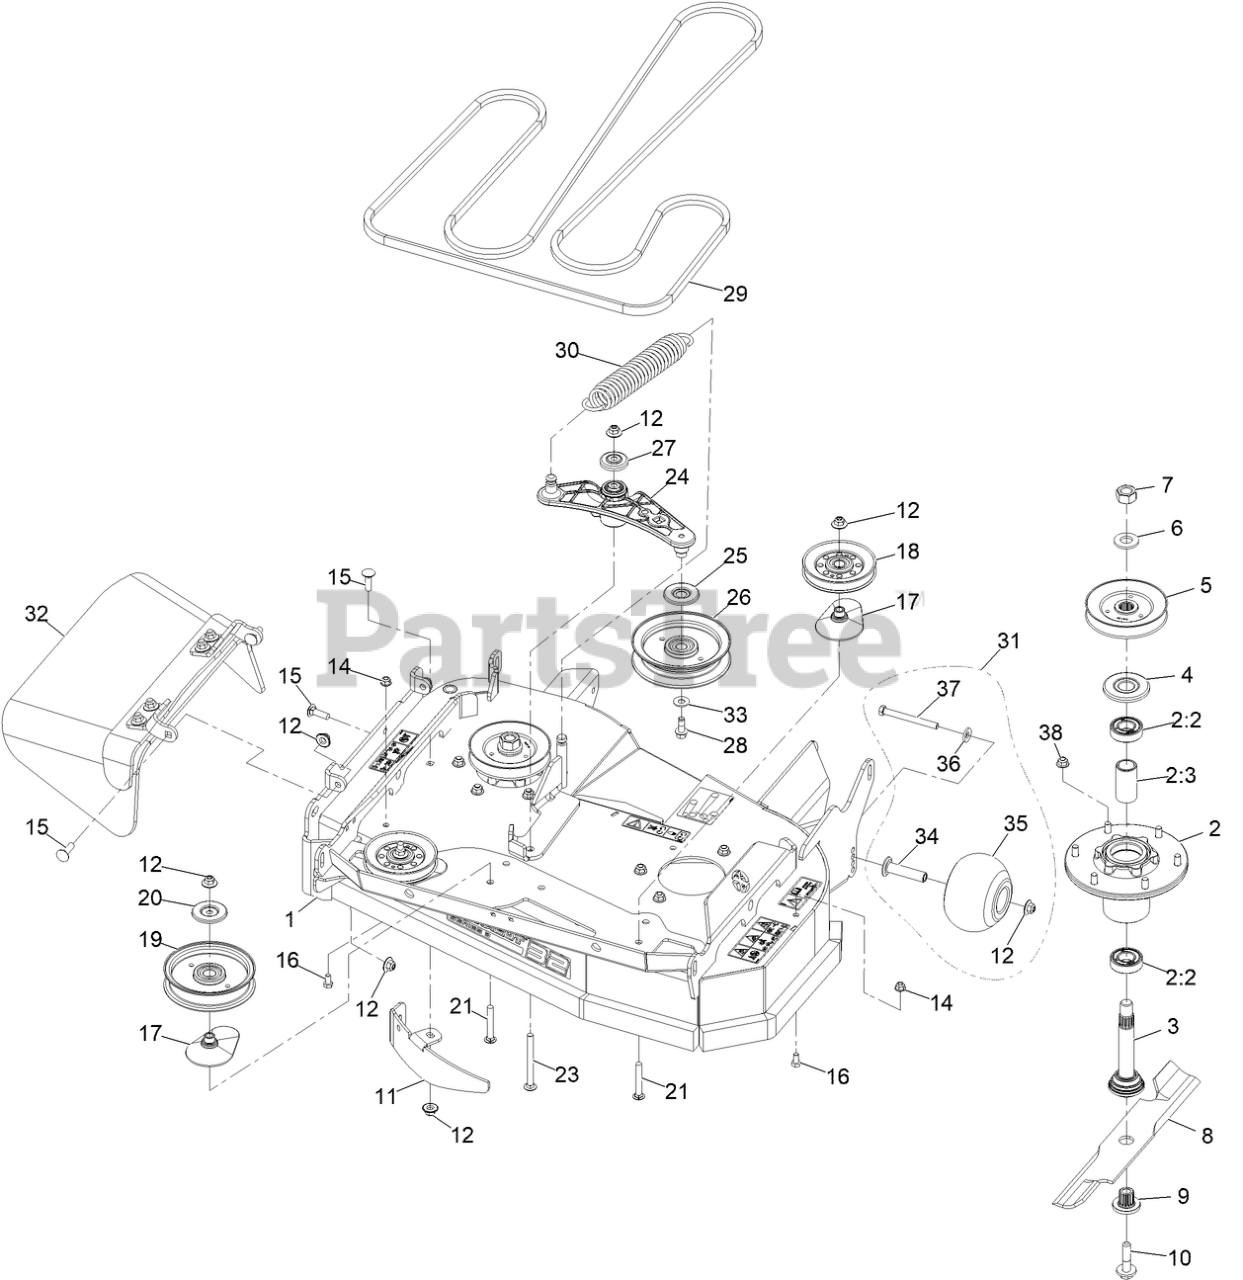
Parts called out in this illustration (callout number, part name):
1	ASM-DECK DECALS 32
2	ASM-Cutter Hsg With Bearings
2:2	BEARING-BALL
2:3	SPACER-BEARING
3	ASM-SPINDLE AND SEAL
4	GUARD,BEARING TOP .989
5	SHEAVE-BLADE DRIVE
7	NUT-HEX
9	BUSHING,SPLINED
10	SCREW,SEMS 1/2-20 X 2.19
11	BAFFLE, DOGLEG
12	Nut-Nyloc 3/8-16 Flg
14	NUT-HF, NI
15	BOLT-CARR
16	SCREW-HH
17	SPACER-PULLEY
18	Idler - V 4.13 Eod-A
19	Pulley-Idler, Flat
20	SHIELD-DUST
21	SCREW-CARR
23	SCREW-CARR
24	ASM.-ARM, IDLER
25	SHIELD-GUARD, DUST
26	IDLER-PULLEY, FLAT
27	GUARD-TOP
28	SCREW-HFH
30	SPRING-EXTENSION
31	KIT, ANTI-SCALP ROLLER
32	RUBBER DEFLECTOR ASM
33	WASHER-FLAT
34	AXLE, ROLLER
35	ROLLER-SCALP, ANTI
36	WASHER-BELLEVILLE
37	SCREW-HH 3/8-16 X 3 3/4 GR 8
38	NUT-HF, NI
